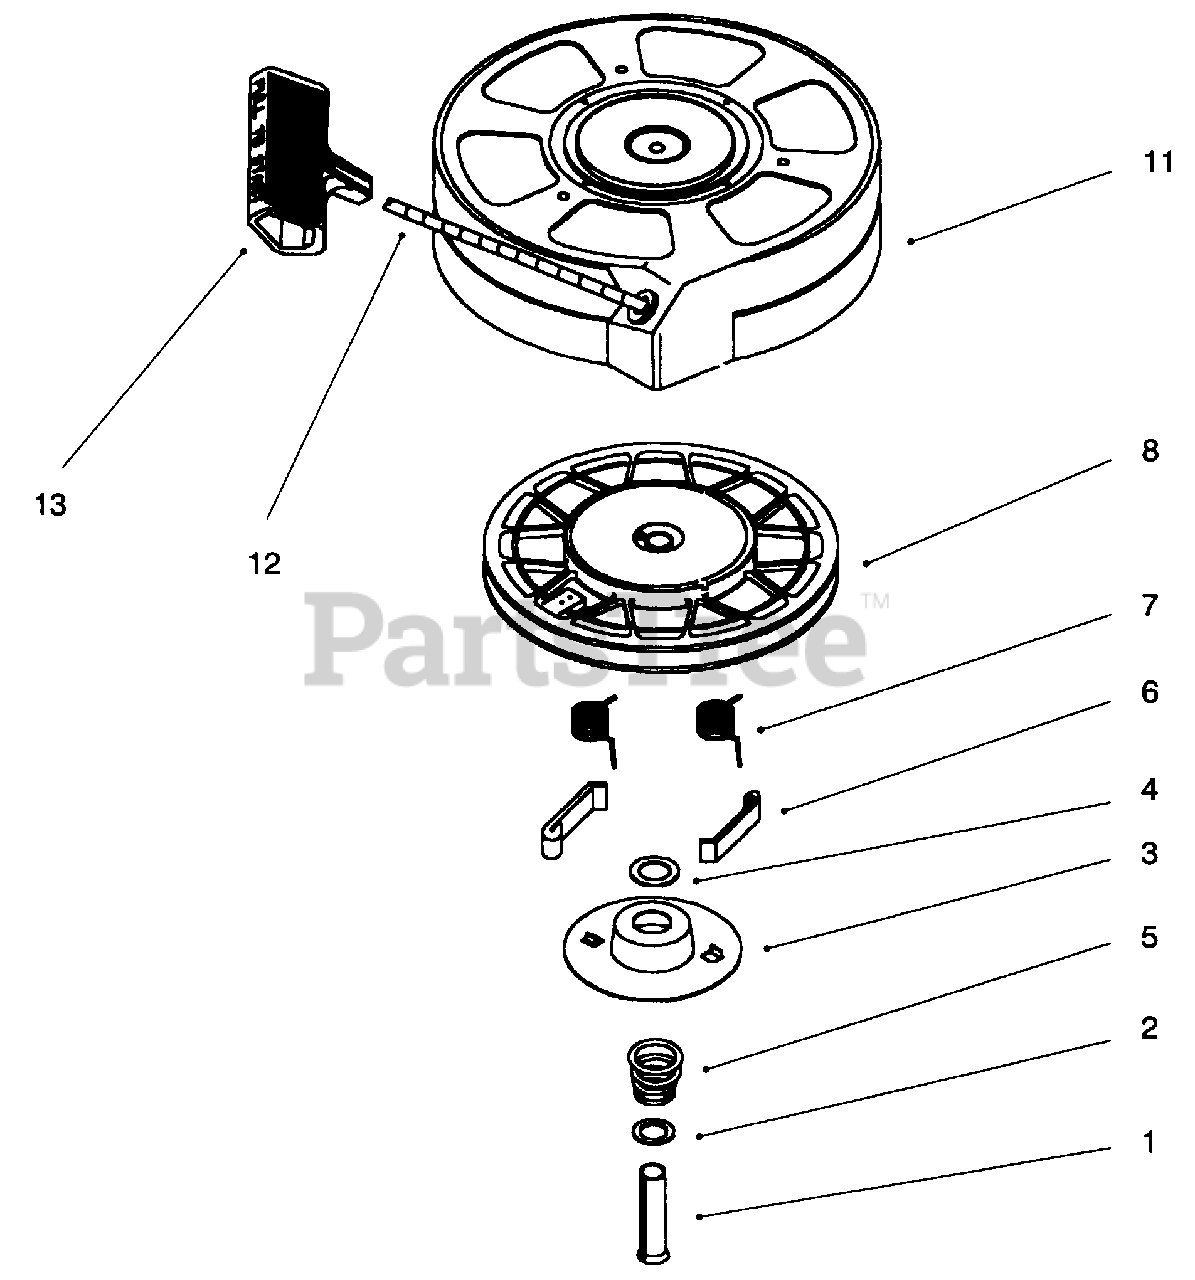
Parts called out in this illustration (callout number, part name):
1	Spring Pin (Incl. 4)
3	Retainer
5	Brake Spring
6	Starter Dog
7	Dog Spring
8	Pulley & Rewind Spring Ass'y.
11	Starter Housing Ass'y (40 degree grommet)
12	Starter Rope (98" X 9/64" dia.)
13	Starter Handle
